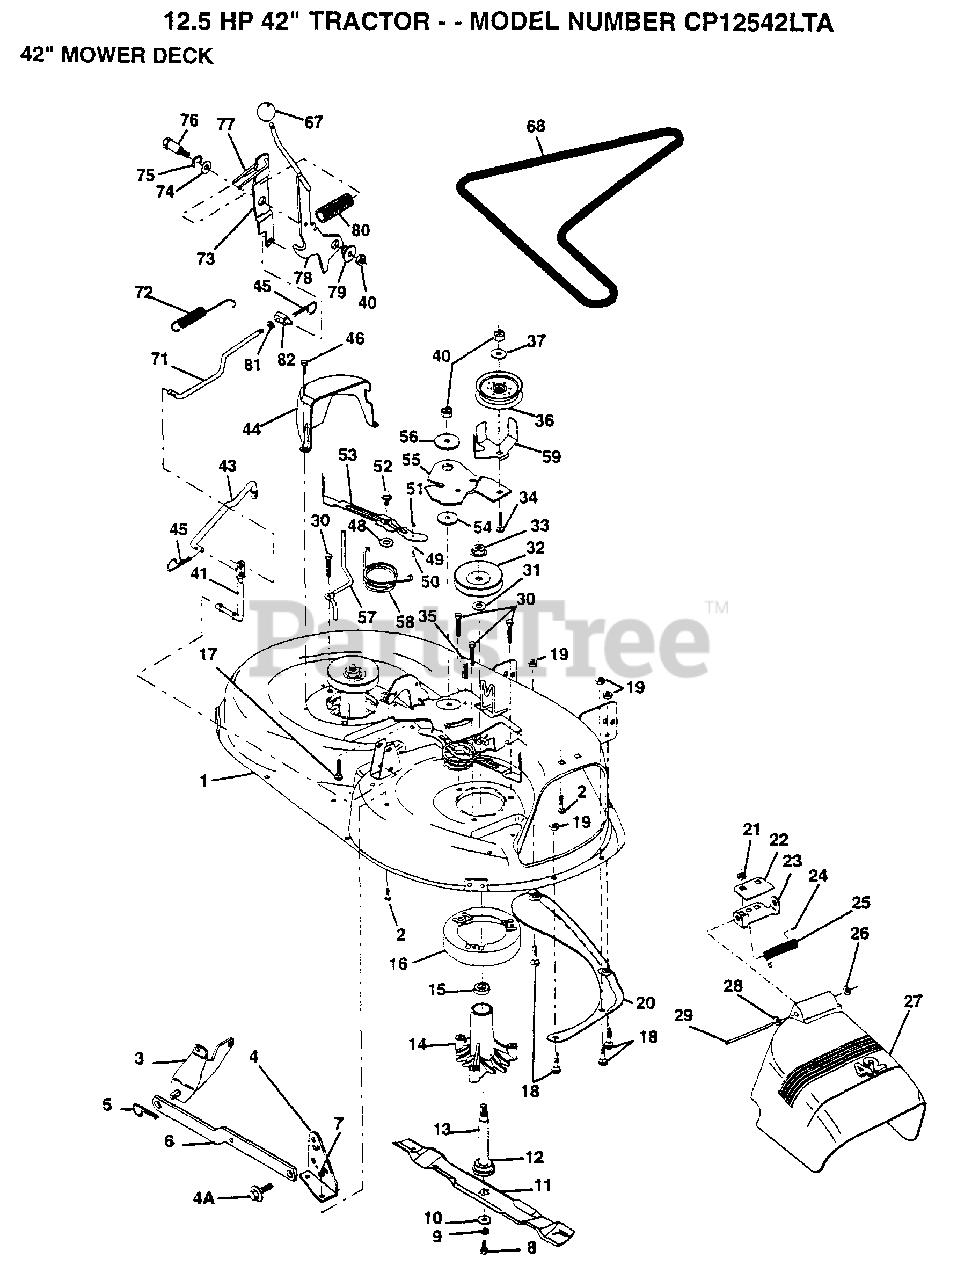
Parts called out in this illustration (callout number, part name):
2	BOLT
3	BRKT ASM SWAY BAR
4	BRKT DECK SW BAR
4A	BOLT SHD 5/16-18
7	NUT
8	BLADE BOLT
10	WASHER.HARD.BLADE
11	"BLADE.42"" MULCHER"
12	BEARING.BALL
14	HSG ASM MANDREL
15	BEARING
16	STRIPPER RND MWR
17	BOLT RDHD 3/8-16
18	BOLT
19	NUT
21	NUT
22	STIFFENER BRKT
23	DEFLECTOR BRKT
24	CAP-SLEEVE LT
25	SPRING TORSION
26	NUT PUSH M
27	DEFLECTOR.SHIELD
28	WASHER
29	HINGE ROD
31	WASHER
34	BOLT
35	XMAS TREE FASTNER
36	FLAT IDLER PULLEY
37	WASHER
40	NUT
41	PIVOT ROD
43	ROD CLUTCH W/NIBS
44	GUARD MAND LH BLK
45	RETAINER M
46	SCREW.1/4-20X5/8
48	HARD SMALL WASHER
50	SHOULDER BOLT
51	LOCKNUT
52	BOLT.SHLD.5/16-18
53	BRAKE PAD ARM ASM
54	HARDENED WASHER
56	SPACER RETAINER
57	KEEPER BELT LH 42
58	SPRING TORSN BRAK
59	GUARD IDLER TUV
67	KNOB T(3/8 HOLE)
68	BELT-V MWR 82.625
71	ROD CLUTCH 38/42
72	RETURN SPRING
73	CLUTCH ARM SECOND
74	WASHER
75	RING
76	SHOULDER BOLT
77	SPRING KEEPER
79	BUSHING
81	NUT
82	TRUNION ADJ
